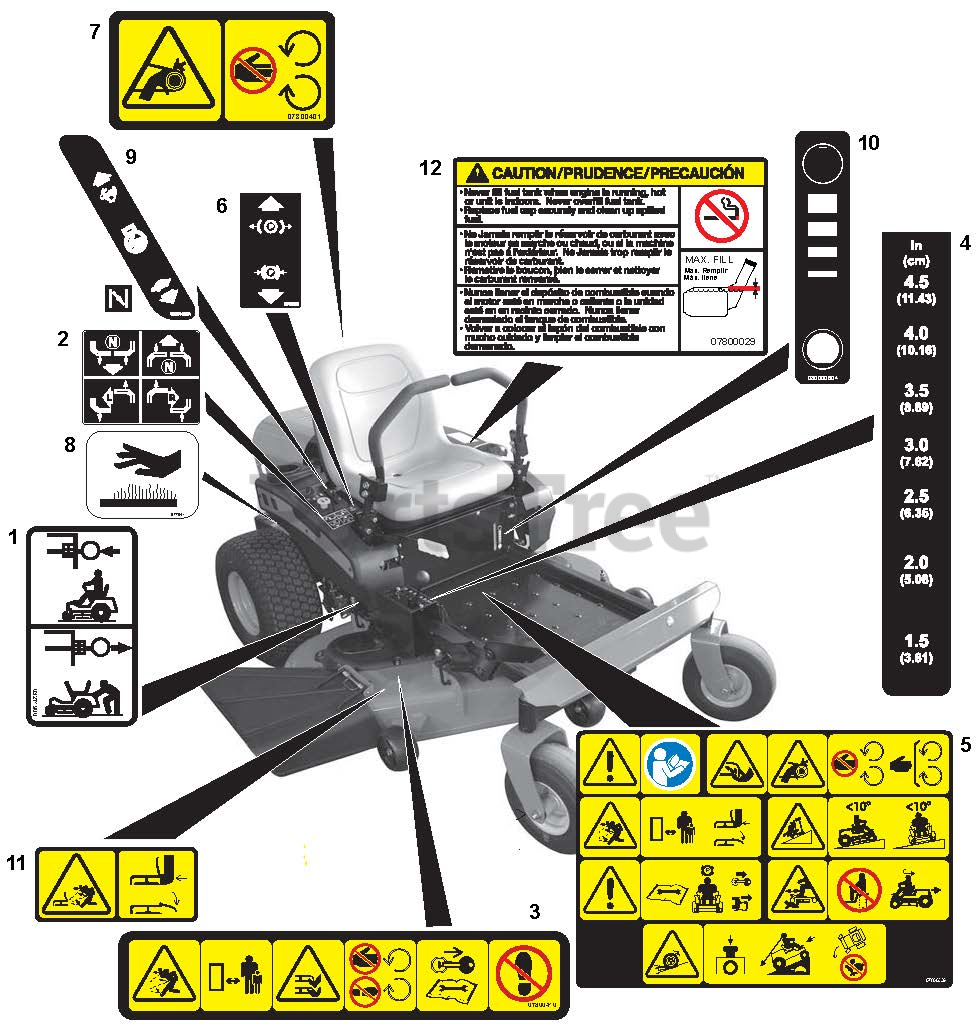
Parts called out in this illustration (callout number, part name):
1	DECAL, TRANSMISSION DISCONNECT
2	DECAL, INSTRUCTIONAL-STEERING
3	DECAL, DECK SAFETY
4	DECAL, HEIGHT OF CUT
5	DECAL, MAIN SAFETY
6	DECAL, PARKING BRAKE LEVER
7	DECAL, SAFETY - GUARDING
8	DECAL, HOT SURFACE
9	DECAL, SPEED CONTROL
10	DECAL, FUEL LEVEL
11	DECAL, SAFETY - DECK GUARDING
12	DECAL-FUEL, WARNING
